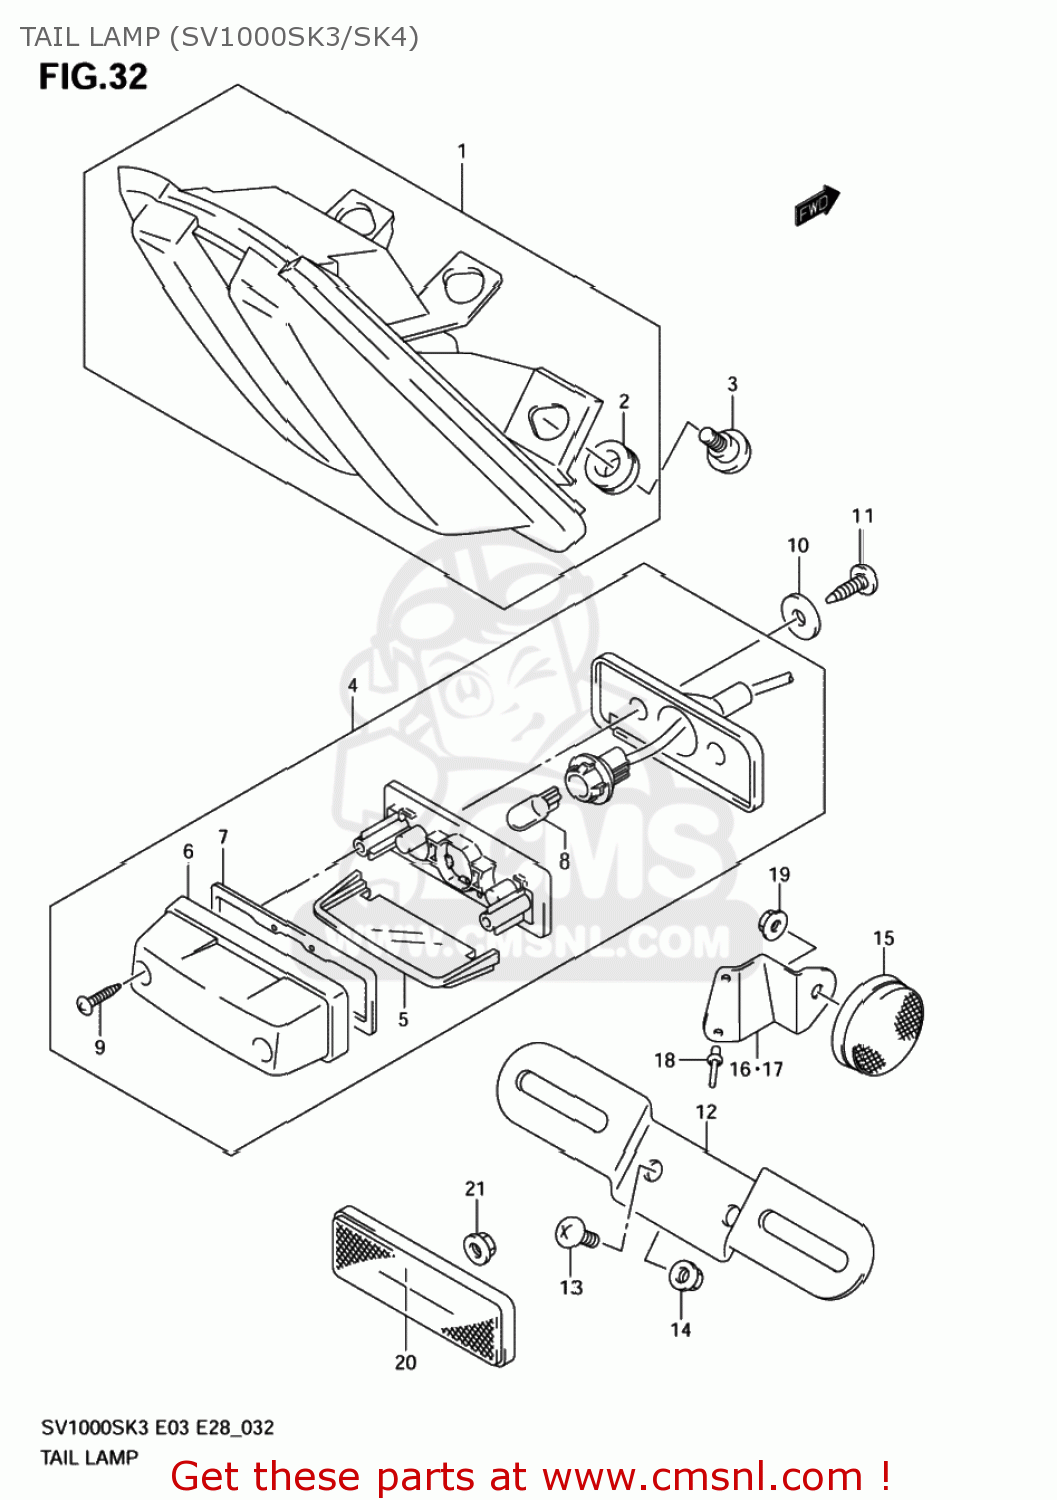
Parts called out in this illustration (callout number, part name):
1	LAMP ASSY,RR COMBINATION
2	CUSHION
3	SCREW(6X22.5)
4	LAMP ASSY,LICENSE
5	LENS
6	COVER
7	GASKET (NAS)
8	BULB(12V5W)
9	SCREW
10	WASHER(5.5X20X1.2)
11	SCREW
12	BRACKET,LICENSE PLATE
13	SCREW
14	NUT
15	REFLECTOR ASSY,RR SIDE
16	BRACKET,RR SIDE RR,R
17	BRACKET,RR SIDE RR,L
18	RIVET
19	NUT
20	REFLECTOR ASSEMBLY,REAR
21	NUT
